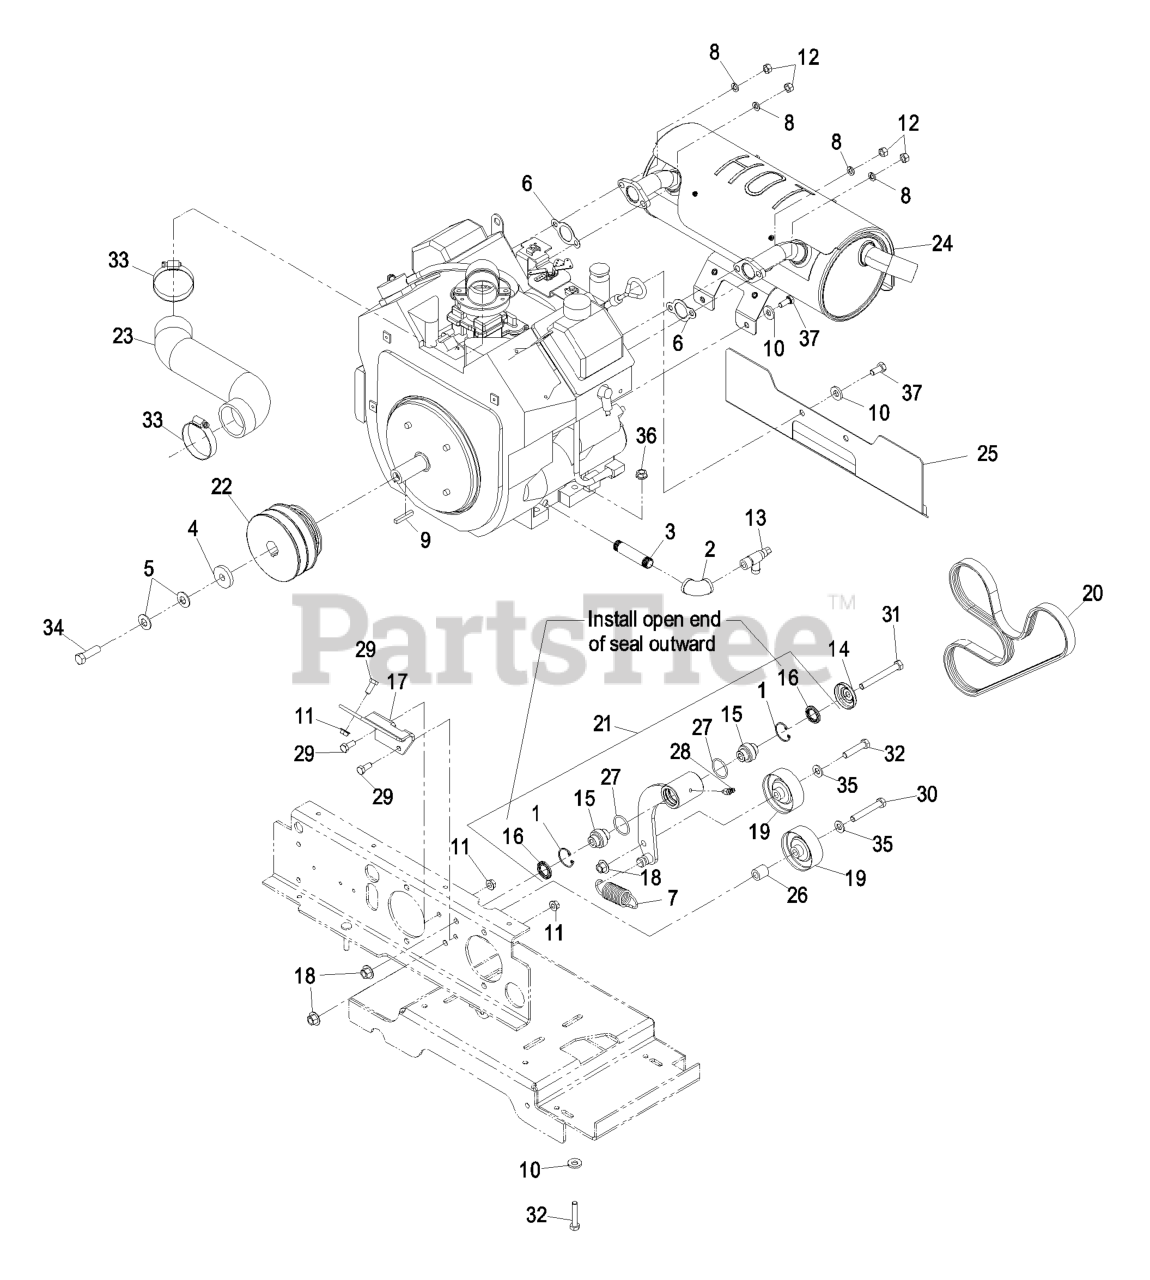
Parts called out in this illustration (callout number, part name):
1	RING-SNAP
2	ELBOW-90 DEG
3	NIPPLE
4	WASHER-CLUTCH
5	WASHER-SPRING
7	SPRING-IDLER
8	WASHER-LOCK
9	KEY-SQUARE
10	WASHER-BELLEVILLE
12	NUT-HEX
13	VALVE-DRAIN, OIL
14	GUARD-TOP
15	BEARING-SPHERICAL
16	SEAL-LIP, SINGLE
17	BRACKET-FILTER, AIR
18	NUT-FLANGE
20	BELT-V
21	IDLER ASM
23	HOSE-AIR INTAKE
25	SHIELD-EXHAUST
26	SPACER-MOUNTING, STEERING
28	FITTING-LUBE, 45 DEG
29	SCREW-HH
30	BOLT-CARR
31	SCREW-HH
32	SCREW-HH
33	CLAMP-HOSE
34	SCREW-HH
35	WASHER-FLAT
36	NUT-HHF, WHIZ
37	SCREW-HH
